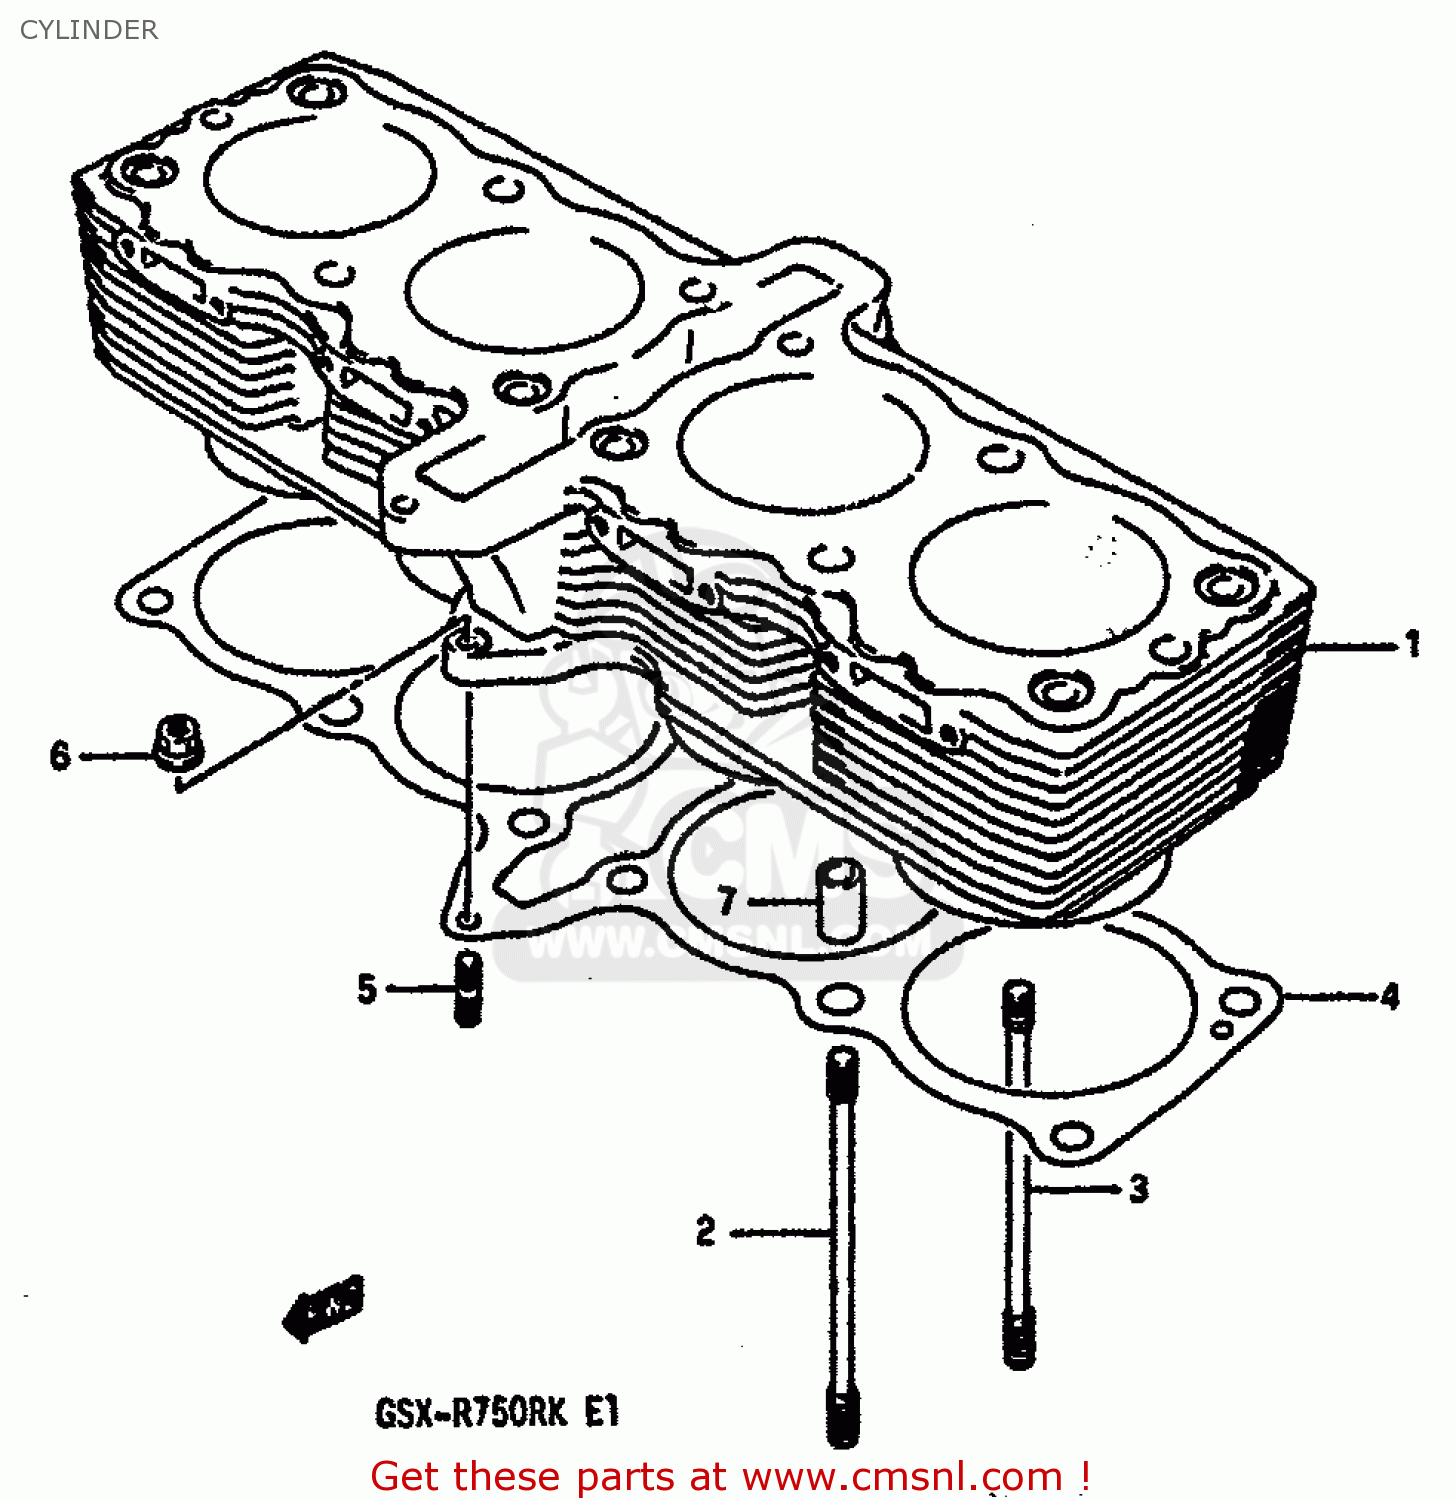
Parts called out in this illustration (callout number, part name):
1	CYLINDER
2	STUD BOLT (L:150)
3	BOLT,STUD
4	GASKET,CYLINDER (NAS)
5	STUD BOLT L:20
6	NUT 6MM
7	PIN
